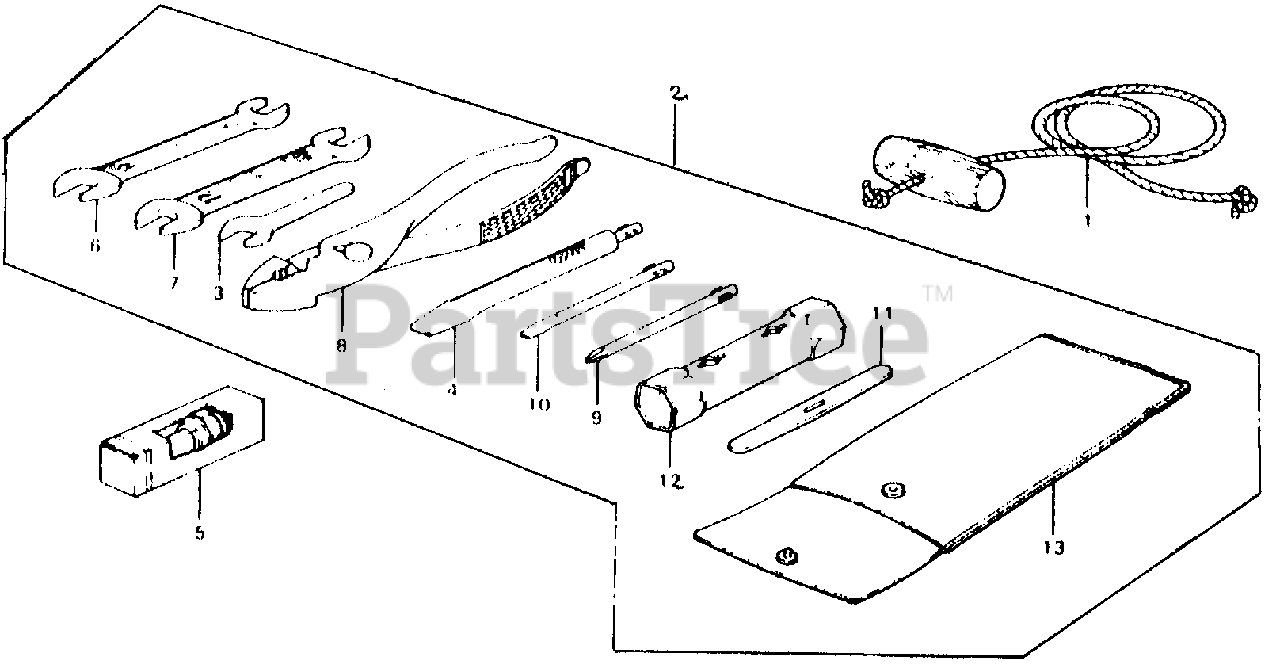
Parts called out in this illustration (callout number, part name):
1	ROPE, STARTER
2	TOOL KIT (N/A: SEE COMPONENTS)
3	SPANNER (8MM) (NOT AVAILABLE)
4	SCREWDRIVER, CHECK BOLT
5	SPARK PLUG (DR-5HS) (NGK)
6	SPANNER (9X12)
7	SPANNER (10X12)
8	PLIERS (135) (KOWA)
8	PLIERS (135)
9	DRIVER 1, PLUS SCREW (NO.2)
10	DRIVER 3, MINUS SCREW (NO.2)
12	WRENCH, BOX (P18X19)
